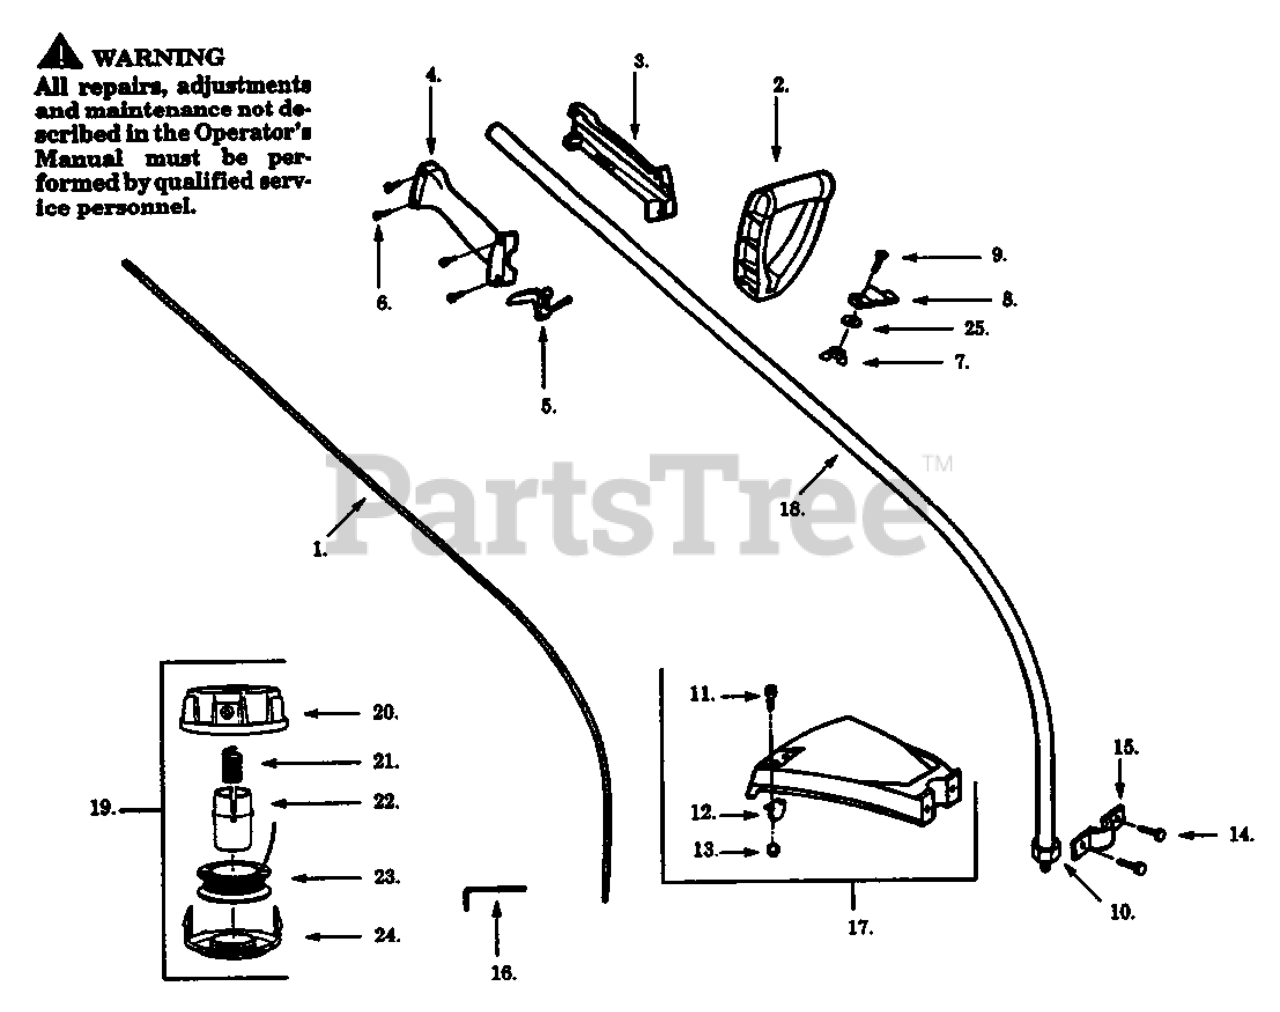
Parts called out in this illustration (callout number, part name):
1	FLEX SHAFT
2	"D" HANDLE
3	THROTTLE HOUSING LEFT
4	THROTTLE HOUSING RIGHT
5	THROTTLE LEVER
6	SCREW - THROTTLE HOUSING
7	NUT-"D" HANDLE
8	CLAMP-ASSIST HANDLE
9	BOLT, TYPE 2
12	LIMITER-LINE
13	LOCKNUT - LINE LIMITER
14	SCREW - SHIELD
15	BRACKET-SHIELD
16	HEX WRENCH 5/32
17	SHIELD KIT ASSEMBLY
18	DRIVE SHAFT HOUSING
19	Cutting Head Ass'y.
20	Hub Ass'y.
23	Spool w/Line
